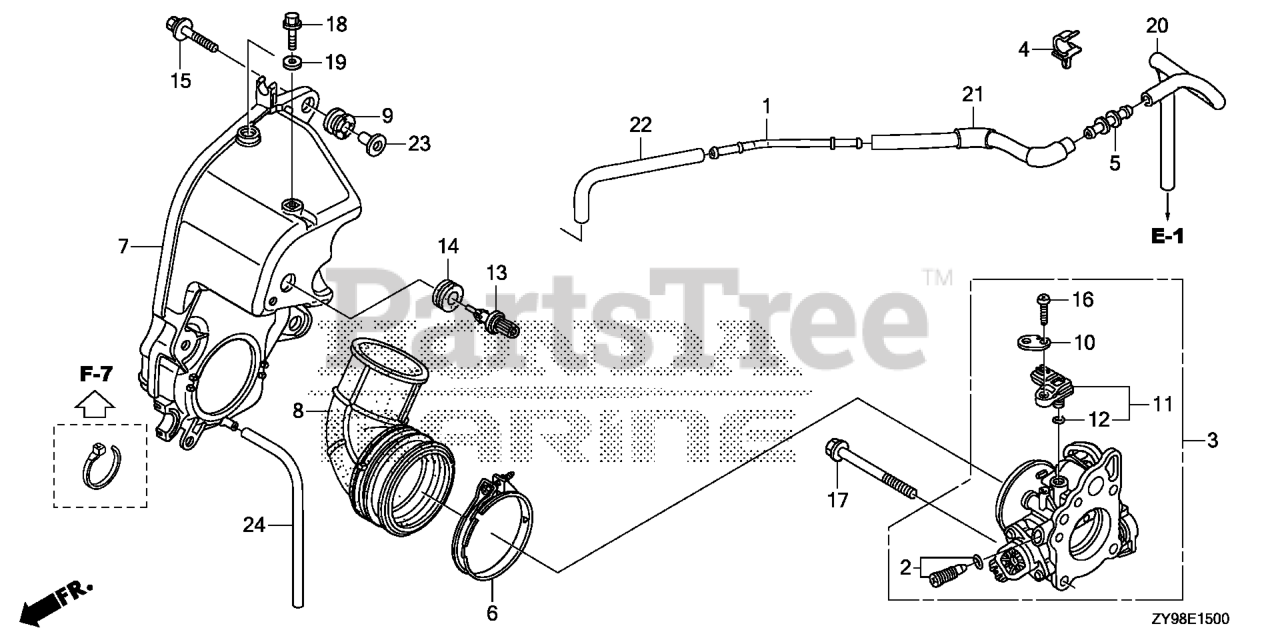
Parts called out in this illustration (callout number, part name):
1	PIPE, BREATHER
3	BODY ASSY., THROTTLE
4	CLAMP B, FUEL TUBE
5	JOINT, FUEL TUBE
6	BAND, AIR FLOW
7	CASE, MUFFLER
8	GROMMET, MUFFLER
9	GROMMET, ELECTRONIC PARTS CASE
10	BRACKET, SENSOR WIRE
11	SENSOR ASSY., MAP
13	SENSOR ASSY., AIR TEMPERATURE (MATSUSHITA DENSHI)
13	SENSOR ASSY., AIR TEMPERATURE
14	GROMMET, TA SENSOR
15	BOLT-WASHER (6X27) (CT200)
15	BOLT-WASHER (6X27)
16	SCREW, PAN (5X18)
17	BOLT, FLANGE (8X60)
18	BOLT, FLANGE (6X25)
18	BOLT (6X25)
19	WASHER, PLAIN (6MM)
20	TUBE A, BREATHER
21	TUBE B, BREATHER
22	TUBE C, BREATHER
23	COLLAR, MODULE IGNITION CONTROL CASE (CDI)
23	COLR, CDI UNIT CASE
23	COLLAR (12X6.5)
24	BULK HOSE, VINYL (4X7X8000) (95003-07(95003-07001-60M) (CARBURETOR NO.)
